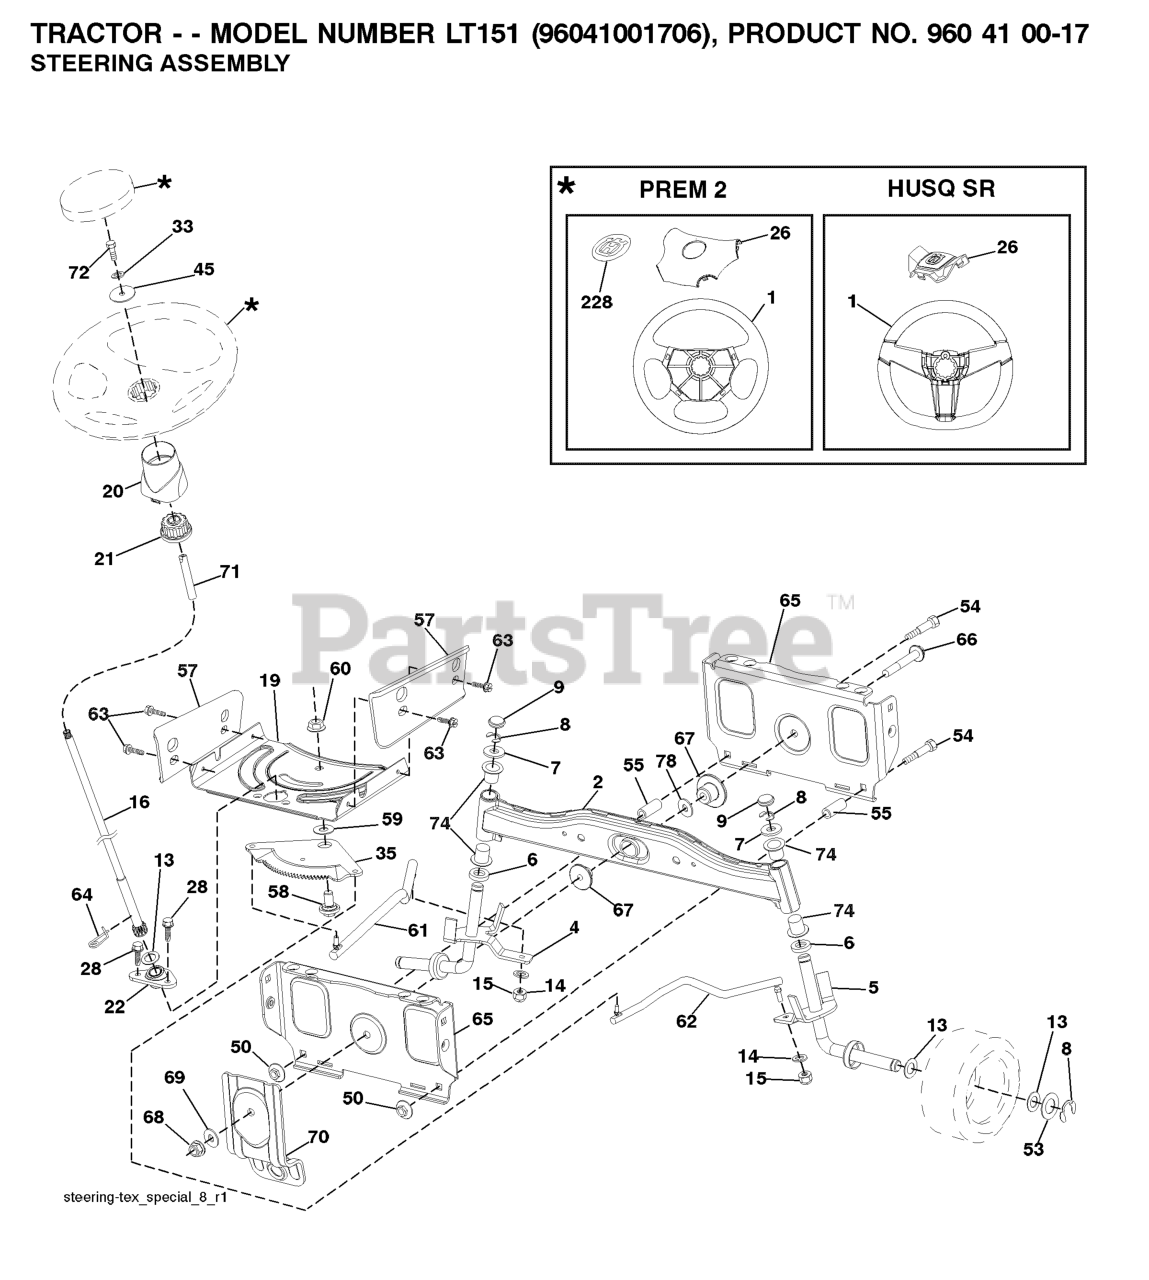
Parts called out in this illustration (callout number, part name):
1	RP WHEEL.STEER.HUSQ.PREM.OVMLD
2	AXLE HALF ASM-WELDED
4	SPINDLE.WELDED.LH.15"TEX
5	SPINDLE.WELDED.RH.15"T
6	THRUST WASHER
9	CAP.SPINDLE.BLACK
14	WASHER, LOCK 3/8
15	NUT CROWNLOCK 3/8-24
16	SHAFT STEERING
19	PLATE.STEER.DDL.NLT/NG
20	BOOT, STEERING
21	ADAPTER, WHEEL STNG..
22	BUSHING.ASM.STEERING.A
26	RP INSERT.CAP.WHL.STRG.HUSQ.
28	SCREW, 3/8-16X3/4
33	WASHER.LOCK.HVY.HLCL.SPR.5/16
35	GEAR.SECTOR.PLATE.DDL.
45	WASHER.11/32
50	NUT LOCK FLG 3/8-16 UNC
53	WASHER.HARDENED
55	SPACER.BRACE.AXLE
57	BRACKET.UPSTOP.TEX
58	BOLT.SHOULDER.SECTOR.P
59	WASHER.THURST.SECTOR.S
60	NUT FLANGE LOCK 5/8-11
61	DRAGLINK.LH.BALLSTUD.D
62	DRAGLINK.RH.BALLSTUD.D
63	SCREW
64	RETAINER.CLIP.SPRING.S
65	BRACE.AXLE.FRONT.NLT/N
66	BOLT HEX FGHD 7/16-14 X 3 SERR
67	BUSHING.PM.FRONT AXLE
68	NUT.LOCK.FLANGE.7/16
69	WASHER.1.5X.505X.118
70	BRKT.DECK.SUSPENSION.F
71	SHAFT EXTENSION STEERING
72	BOLT YT
74	BRNG T
78	THRUST WASHER
228	DECAL.WHEEL.STRG.LGN.H
